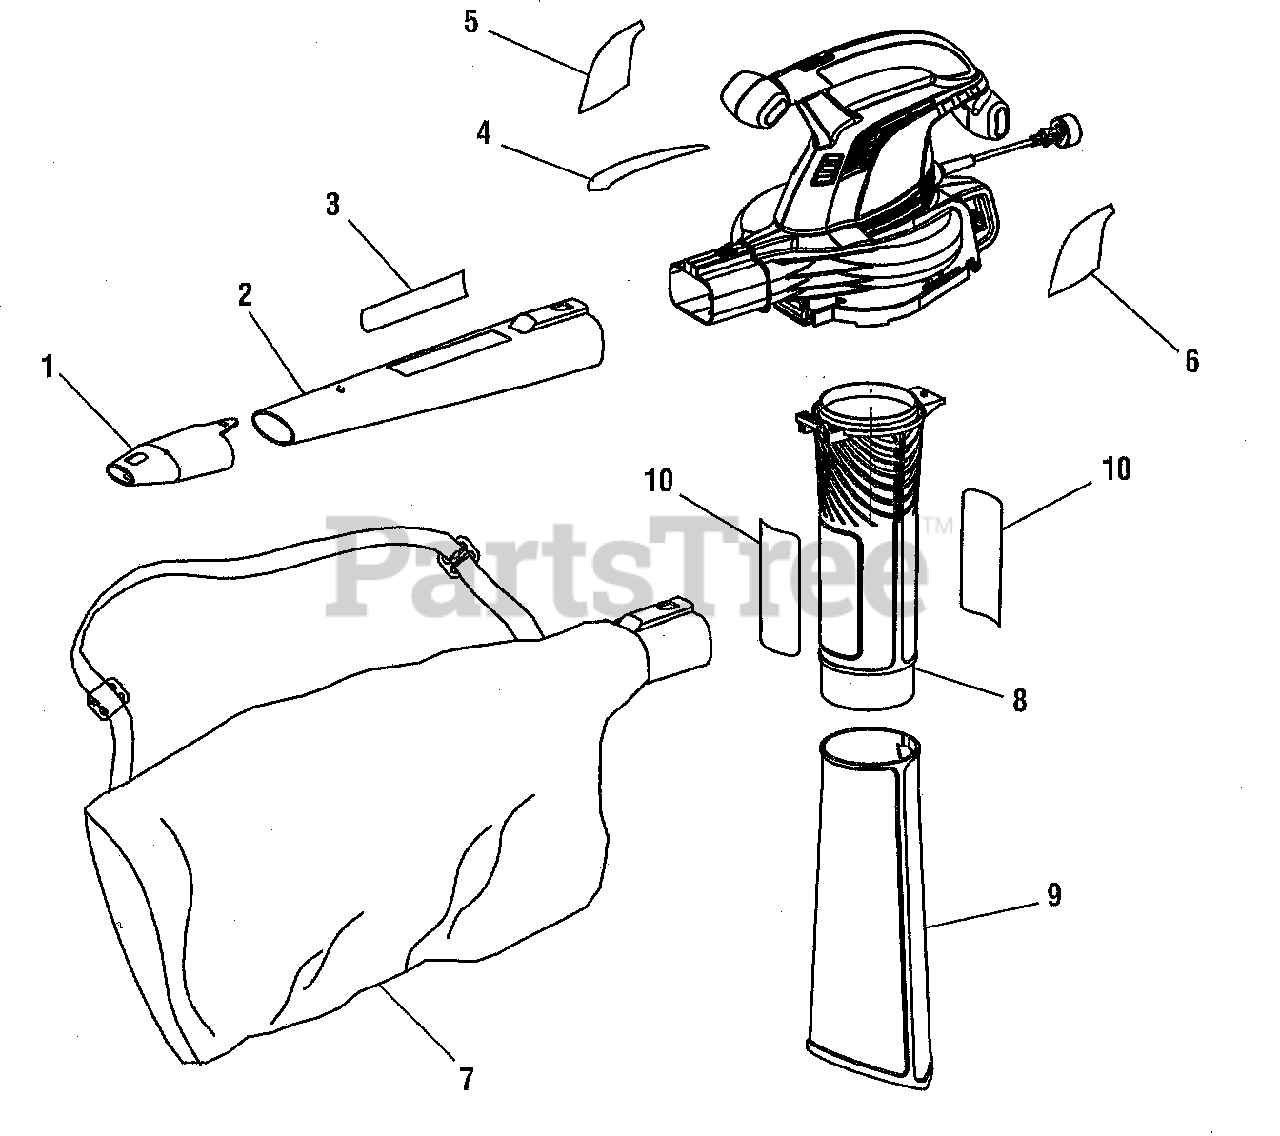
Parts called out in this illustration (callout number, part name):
1	High Velocity Nozzel
2	Blower Tube
3	Logo Label (Blower Tube)
7	Vacuum Bag
8	Upper Vacuum Tube
9	Lower Vacuum Tube
10	Logo Label (Upper Vacuum Tube)
